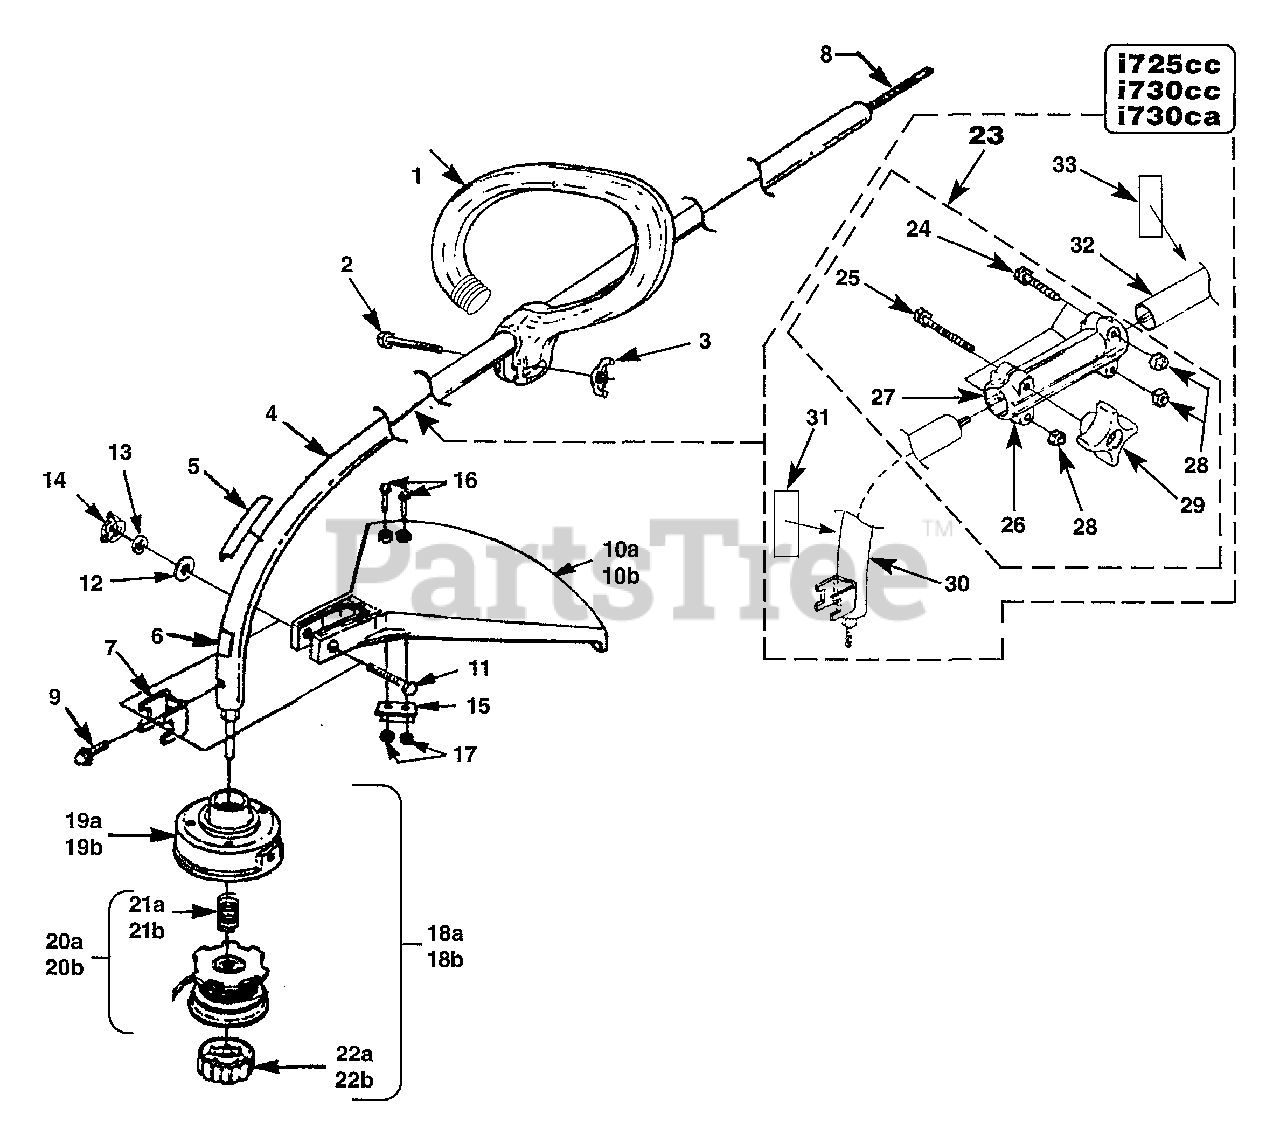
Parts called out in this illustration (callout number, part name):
1	FRONT HANDLE ("D")
2	SCREW-Cap Hex Hd. (10-24 X 2")
3	NUT-Wing (10-24)
4	HOUSING-Drive Shaft
5	DECAL-Starting Inst.
6	DECAL-Warning
7	CLAMP
8	SHAFT-Flexible
9	SCREW-Drilling (#10 X 1/2")
11	SCREW-Cap Hex Hd. (1/4-20 X 2")
12	WASHER-Flat (1/4")
13	WASHER-Lock (1/4")
14	NUT-Hex (1/4-20)
15	BLADE-Cut-Off Kit
16	SCREW-Mech. Hex Hd. (10-24 X 7/8")
17	NUT-Hex (10-24)
18A	STRINGHEAD-Complete (.080" Line)
18B	STRING HEAD COMPLETE (.095" Line)
19A	HOUSING & EYELET (Dual Line)
19B	HOUSING & EYELET (Dual Line)
20A	SPOOL & STRING & SPRING (.080" Line)
20B	SPOOL & STRING & SPRING (.095" Line)
21A	SPRING-Compression
21B	SPRING-Compression
22A	RETAINER-Spool (R.H. Thread, Black)
22B	RETAINER-Spool (R.H. Thread, Black)
23	COUPLER ASSEMBLY
24	BOLT-Hex Hd.3
25	SCREW-Cap Hex (1/4-20 x 2")
26	SPLIT BOOM (L.H.)
27	SPLIT BOOM (R.H.)
28	NUT-Hex (1/4-20)
29	KNOB
30	DRIVE SHAFT HOUSING-Curved (Lower)
31	DECAL-Warning
32	DRIVE SHAFT HOUSING-(Upper)
33	DECAL-Start Instructions
